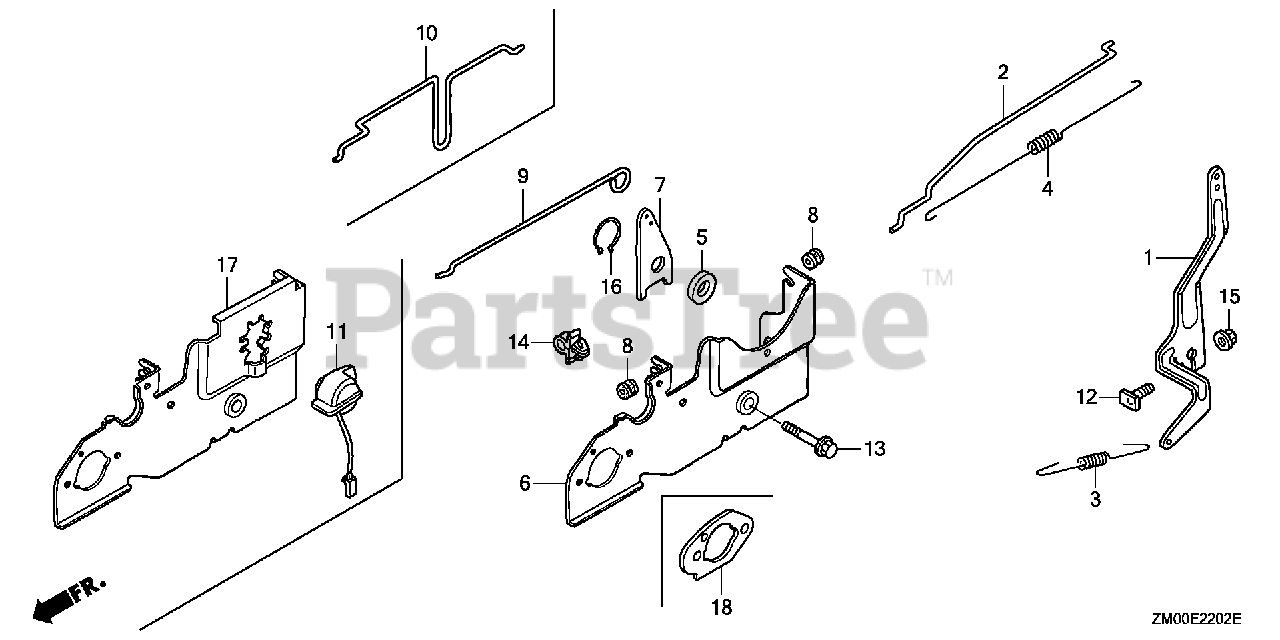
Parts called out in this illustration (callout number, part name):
1	ARM, GOVERNOR
2	ROD, GOVERNOR
3	SPRING, GOVERNOR
4	SPRING, THROTTLE RETURN
6	BASE, CONTROL
12	BOLT, GOVERNOR ARM
13	BOLT, FLANGE (6X45) (CT200)
15	NUT, FLANGE (6MM)
